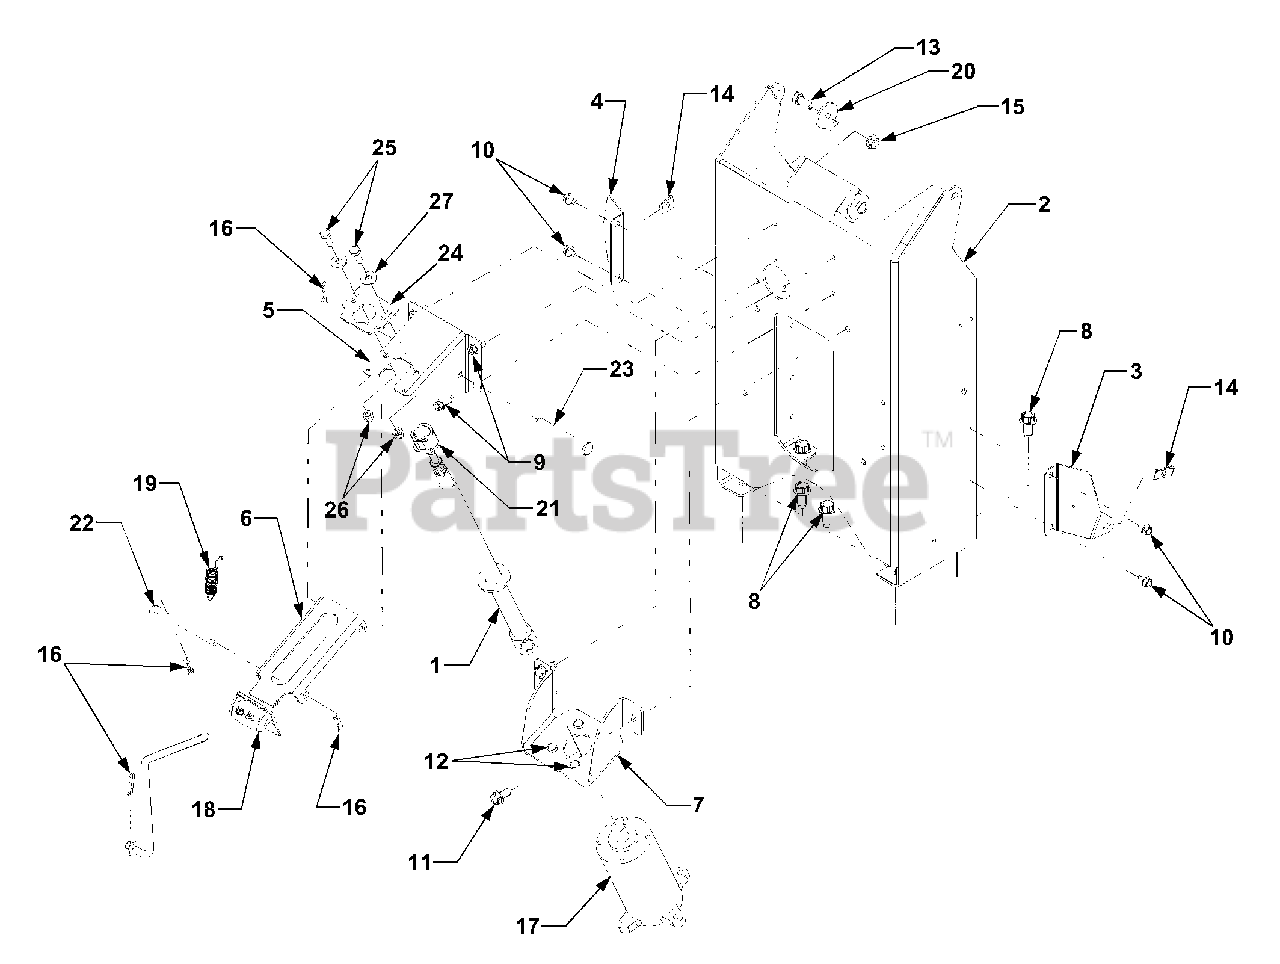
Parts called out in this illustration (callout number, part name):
1	Shaft, Steering
4	Bracket, Dash Mtg. LH
9	Screw, Hex Wash, Hd Tapp 1/4-20 x .75
10	Screw, Hex Wash, Hd Tapp 1/4-20 x .375
11	Screw, Hex Wash, Hd Tapp 5/16-18 x .75
12	Screw, Hex, M6-1 x 16 Hardened
13	Screw, Hex Cap 5/16-18 x .75 GR5
14	Nut, Speed, 1/4-20
15	Nut, Hex Flange Lock, 5/16-18
16	Pin, Internal Cotter
17	Pump, Hydraulic Steering
18	Lever, Parking Brake
19	Spring, Extension
20	Washer, Flat, .33 x 1.25 x .12
21	Bearing, Hex Flange, .75 ID
22	Rod, Parking Brake
23	Pin, Parking Brake Pivot
26	Nut, Hex Insert Lock, 1/4-20
27	Washer, Flat, .28 x .74 x .063
